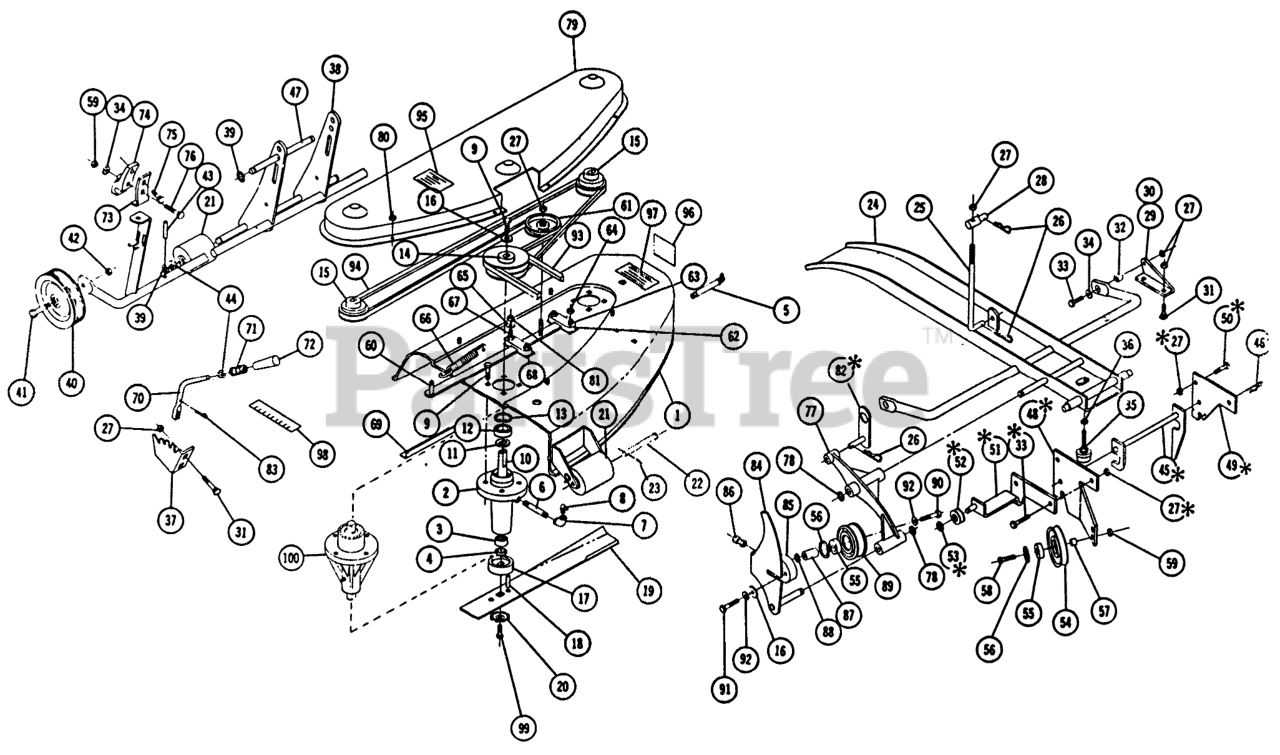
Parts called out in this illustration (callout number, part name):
1	Ass-y. Deck 42" Mower
2	Housing-Spindle
3	NEEDLE BEARING
4	SEAL-OIL
5	Fitting-Grease
6	Nipple 1/8 Pipe x 1" Long
7	ELBOW
8	Fitting-Grease 90deg.
9	Bolt 3/8-16 x 3/4 Hex
10	Shaft Spindle
11	WASHER
12	BEARING-BALL
13	INT SNAP RING
14	Center Pulley
15	End Pulley
16	WASHER
17	Cup-Spindle
18	SPIROL ROLL PIN
19	Blade 14"
20	WASHER
21	Roller
22	CLEVIS PIN
23	Cotter Pin
24	Washer
25	ROD LIFT
26	Hairpin
27	3/8-16 E.S.
28	TRUNNION-LIFT
29	Bracket Deck R.H.
30	Bracket Deck L.H.
31	Bolt-3/8-16 x 3/4
32	SPACER
33	Bolt 3/8-16 x 1
34	Washer
35	LEVELER MOWER
36	Nut, 5/16-18
37	Quadrant
38	Ass-y-Gage Wheel Support
39	E Ring
40	Wheel
41	BOLT-SHOULDER
42	3/8-16 Jam Nut
43	Roll Pin
44	Washer
45	ASSY LATCH & SHAF R
46	Hairpin
47	Pin
48	MOUNTING BRACKET R
49	PLATE-MTG BRKT LH R (NS)
50	Bolt 3/8-16 x 1
51	ASSY BRACKET AND R
52	ROLLER
53	Lock Rod
54	PULLEY IDLER
55	BEARING
56	INTERNAL SNAPRING
57	SPACER
58	Bolt, 3/8-16 x 1/2
60	ASSY BAR IDLER SUPPO
61	Idler Pulley
62	Side Block
63	Bolt-5/16-18 x 1/4
64	Nut
65	Washer
66	SPRING R
67	Bolt-5/16-18 x 1 1/2
68	SLIDE
69	ANGLE
70	FORK
71	Spring
72	GRIP
73	Clip-Axle
74	SUPPORT AXLE
75	Bolt-Carriage
76	Bolt Carriage 3/8-16 x 1
77	ARM PIVOT R
78	RING LAM L 262
79	Cover
80	HEX NUT 10-32 E.S.
81	Nut-Nylok
82	Cam Arm
83	Hairpin
84	ASSEMBLY CAM LEVE R
85	Ass-y Idle Support
86	Nut
87	SPACER
88	Lockwasher-3/8 Int.Tooth
89	PULLEY IDLER
90	Bolt Hex 3/8-16
91	Bolt 3/8-16 x 7/8
92	Lockwasher
93	V BELT
94	V BELT
95	Decal Belt Installation
96	Decal
97	Decal
98	Decal-Height Adj.
99	Bolt 3/8-16 x 7/8
100	Ass-y-Sealed Spindle Bearing
